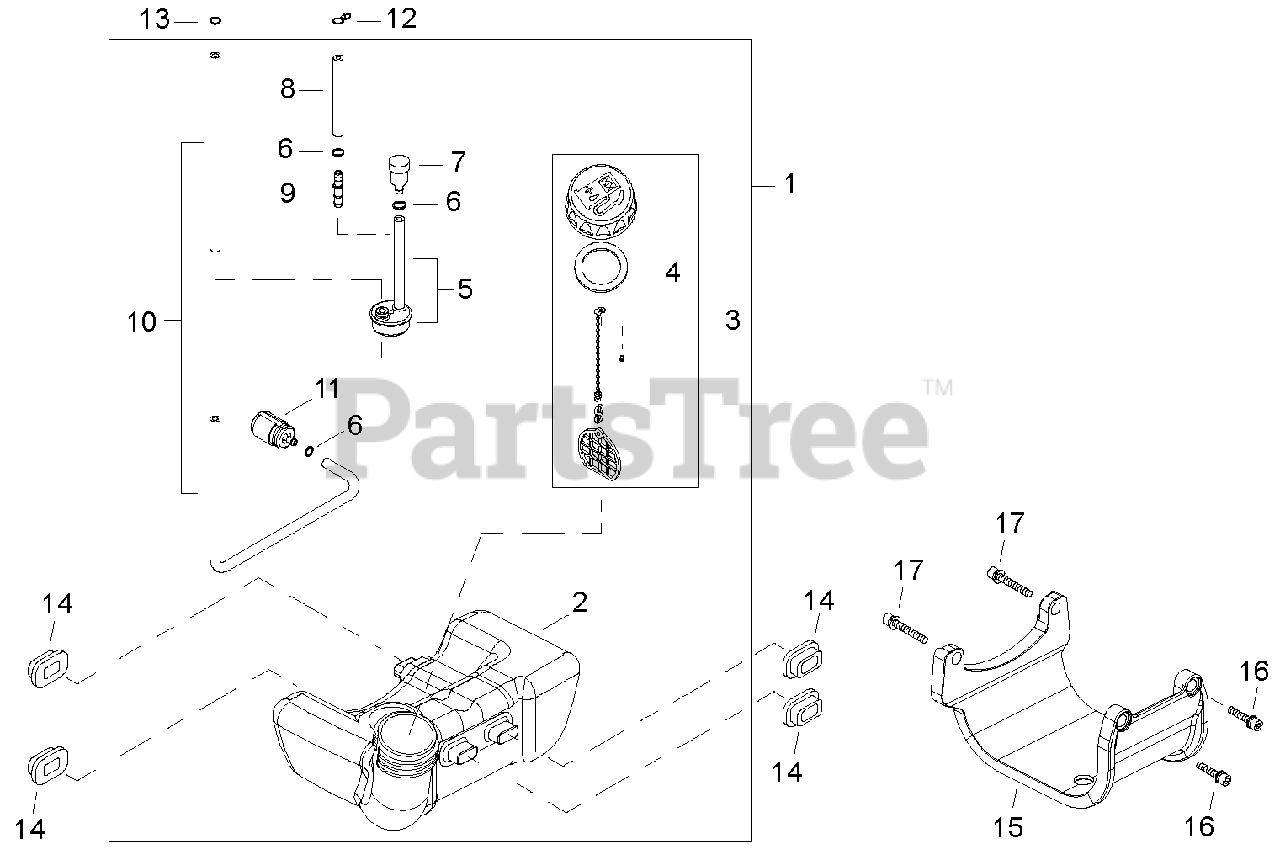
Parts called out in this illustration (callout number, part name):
2	TANK, FUEL
3	CAP ASSY
4	GASKET, CAP
5	VENT PIPE ASSY
6	RING, RETAINING - 6
6-1	FUEL TANK ASSY
7	VENT, FUEL TANK
8	PIPE - RETURN
9	CONNECTOR, PIPE
10	FUEL PICK-UP TUBE
11	FILTER, FUEL
12	CLIP - SPRING
13	RING, RETAINING - 6
14	CUSHION, FUEL TANK
15	GUARD, FUEL TANK
16	SCREW - 5X18
17	SCREW - 5X40
